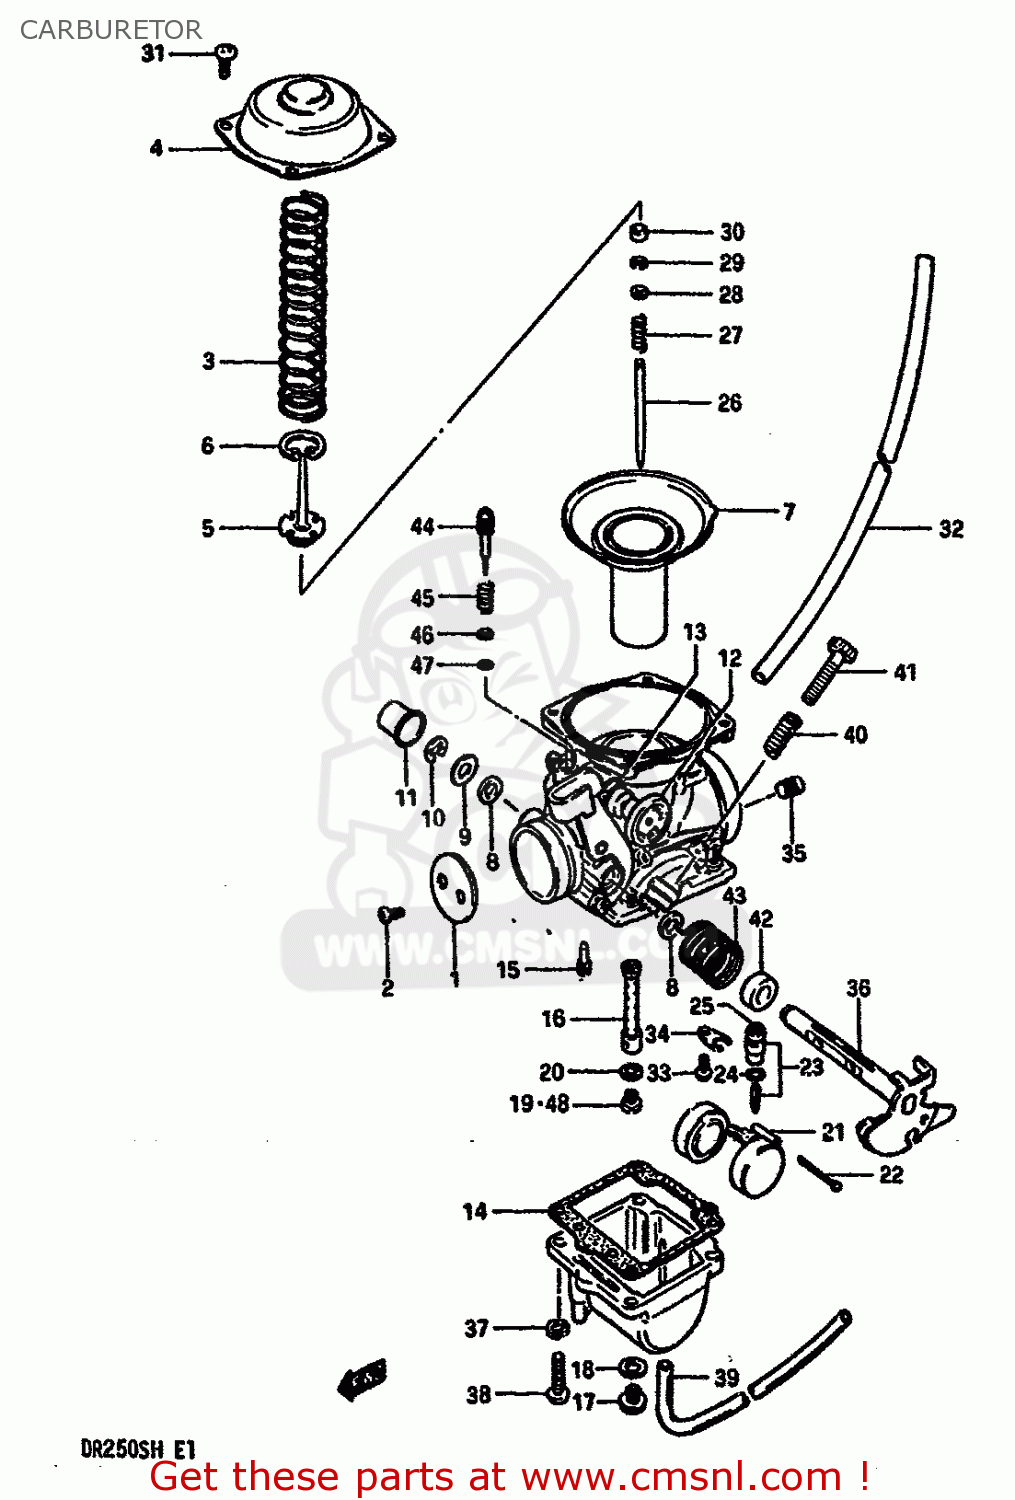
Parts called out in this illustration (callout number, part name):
1	THROTTLE VALVE (100)
2	SCREW
3	SPRING
4	COVER
5	HOLDER,GUIDE
6	E RING
7	DIAPHRAGM ASSY
8	SEAL
9	GASKET,THROTTLE SHAFT (NAS)
10	E RING
11	CAP
12	STARTER VALVE
13	O RING
14	GASKET,FLOAT CHAMBER (NAS)
15	JET,PILOT(42.5)
16	JET, NEEDLE (P-1)
17	PLUG,DRAIN
18	GASKET (NAS)
19	JET,MAIN(125)
20	WASHER,NEEDLE NOZZLE
21	FLOAT
22	PIN,FLOAT
23	VALVE ASSEMBLY,NEEDLE
24	O RING
25	FILTER
26	NEEDLE,JET
27	SPRING
28	WASHER
29	CLIP
30	RING
31	SCREW 5X10
32	HOSE
33	SCREW
34	PLATE
35	JET,AIR(140)
36	SHAFT ASSEMBLY,THROTTLE
37	LOCK WASHER
38	SCREW
39	HOSE
40	SPRING,THROTTLE ADJUST
41	SCREW,THROTTLE STOP
42	RING
43	SPRING,THROTTLE SHAFT
44	SCREW,PILOT AIR
45	SPRING
46	GASKET
47	O-RING
48	JET,MAIN(120)
